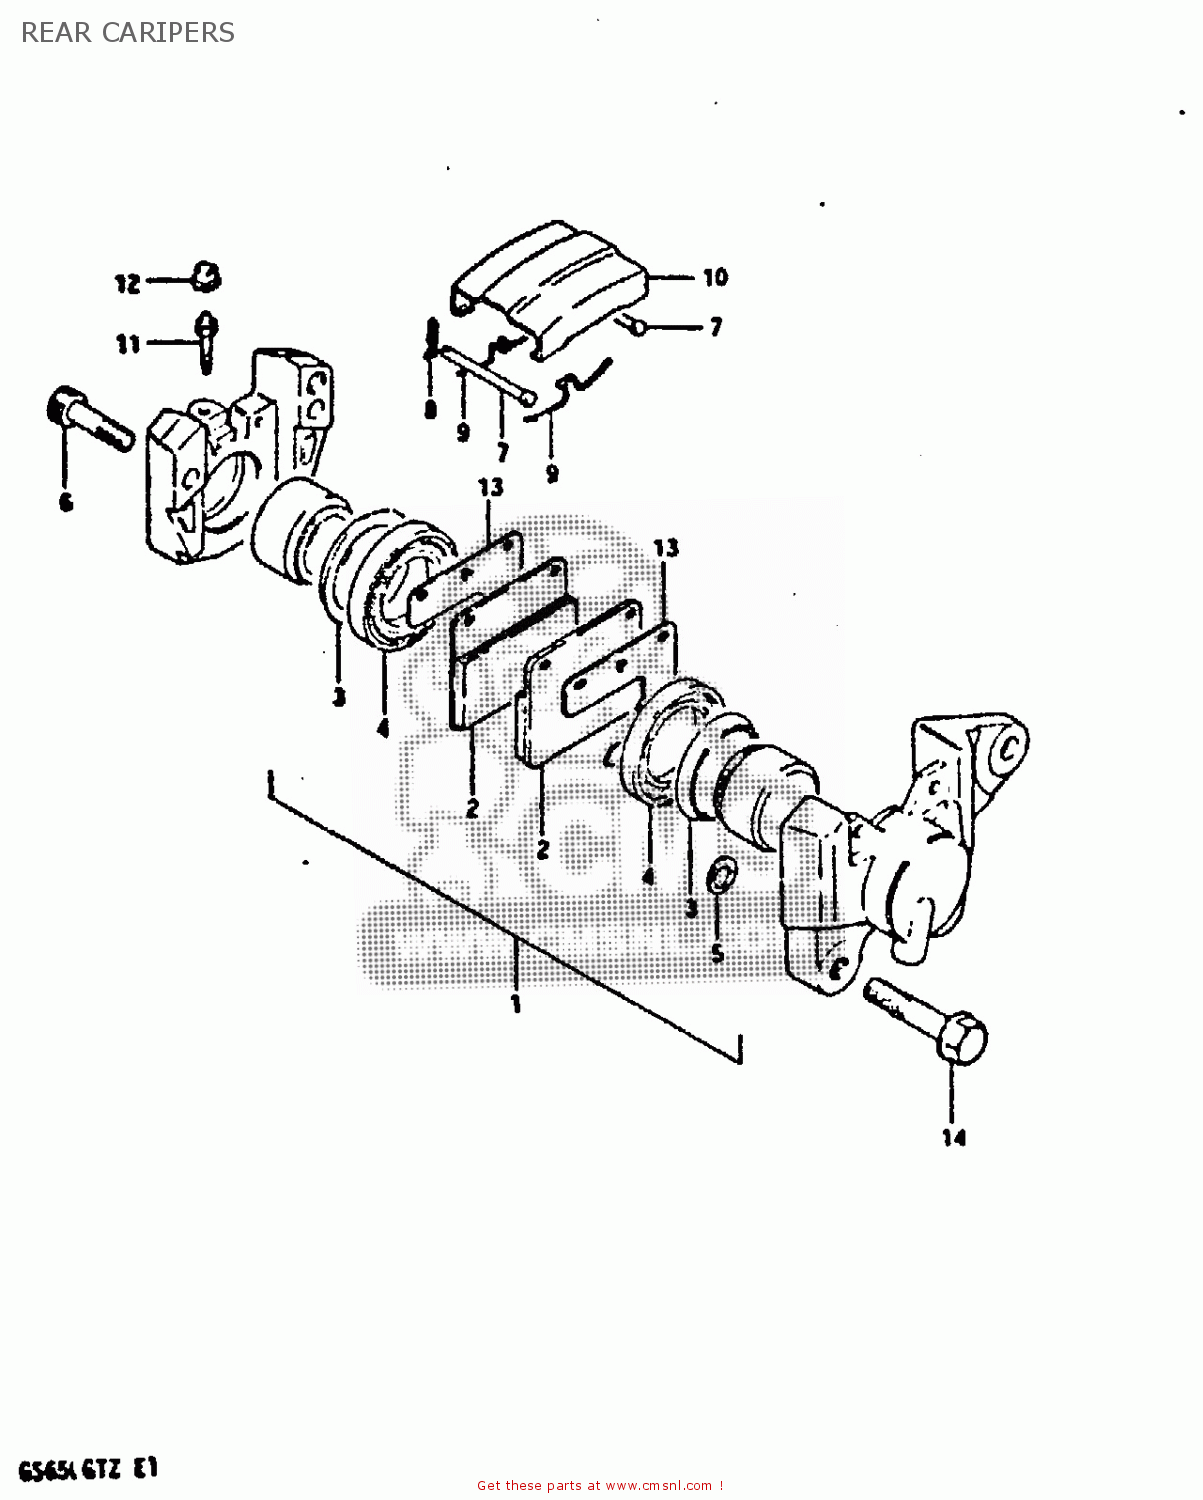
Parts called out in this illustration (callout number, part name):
1	PISTON SET
2	PAD,BRAKE
3	SEAL,PISTON
4	BOOT,PISTON
5	SEAL,JOINT
6	BOLT,CALIPER HOUSING
7	PIN,PAD
8	CLIP,PAD PIN
9	SPRING
10	COVER,DUST
11	BLEEDER
12	CAP,BREATHER
13	SHIM,RR CALIPER
14	BOLT
